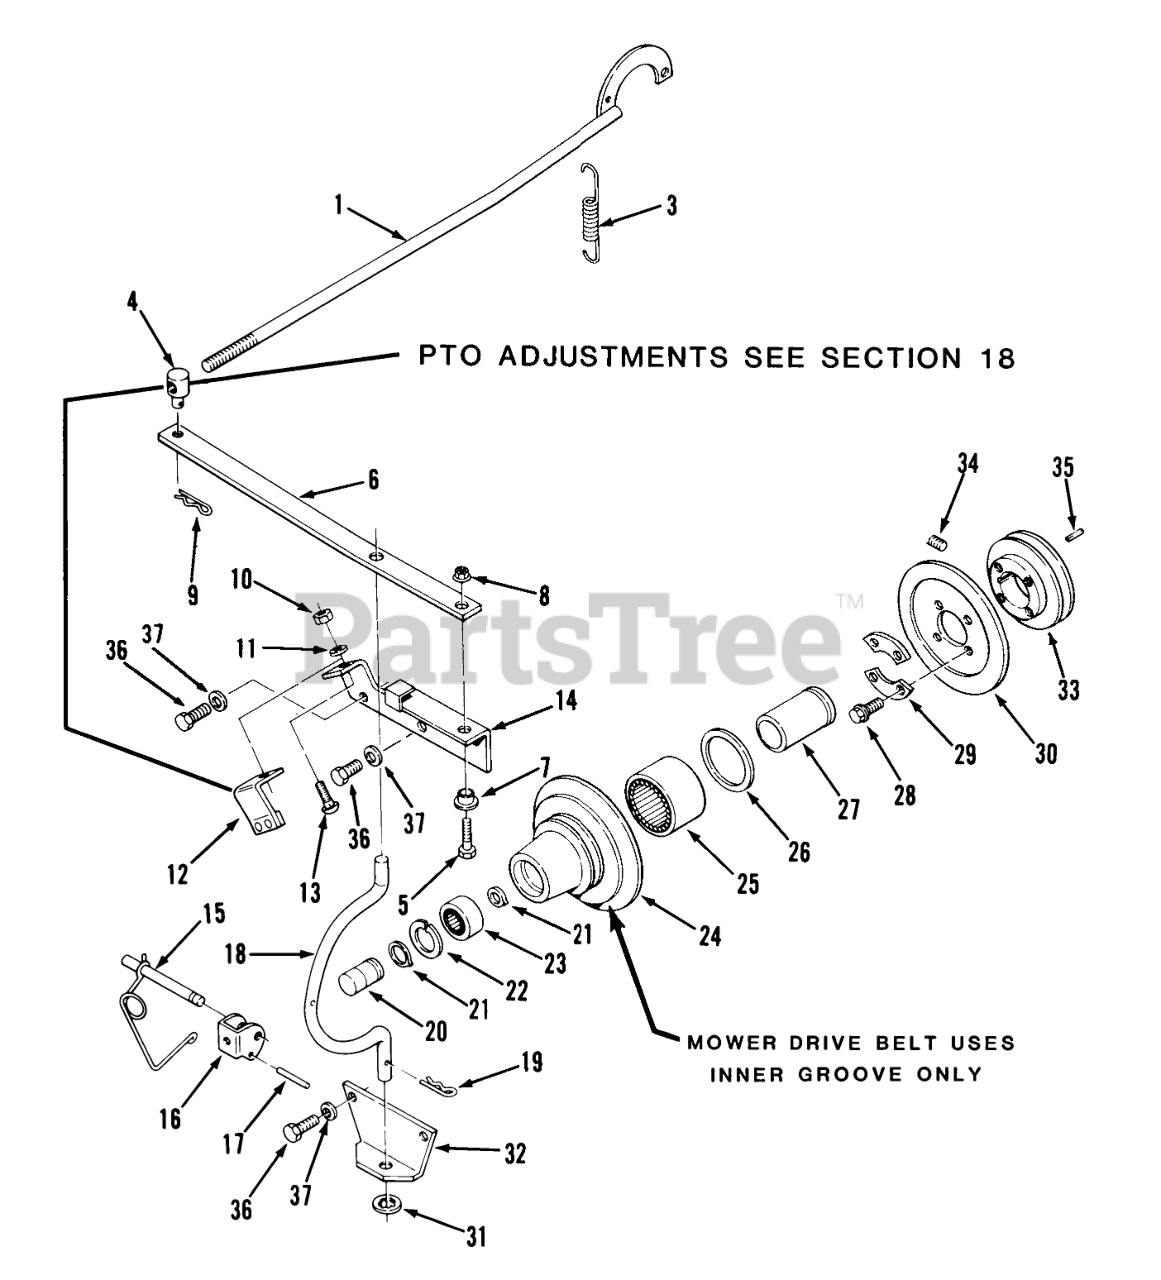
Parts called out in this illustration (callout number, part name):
1	PTO ROD 30209K
3	Spring
4	TRUNNION
5	BOLT
6	PTO ENG BRKT 30210K
7	SPACER-LIFT LINK
8	Nut
9	Hairpin Cotter
10	Nut
11	Washer
12	ASM-Bracket
13	Bolt-Carriage
14	Engine Bracket
15	LOCKING PIN ASM
16	CLEVIS B
18	ROD HOUSING
19	Hairpin
20	SHAFT-PTO
21	RING-SNAP, EXTERNAL
22	Ring-Snap
23	BEARING-BALL
24	Housing-Clutch
25	BRG-NEEDLE OPEN END
26	SEAL-OIL
27	RACE-BEARING
28	H H C S
29	RETAINER
30	Clutch Plate & Facing
31	RING-REINFORCED CIRC
32	Rod Support Housing
33	PULLEY
34	Set Screw
36	7/16-14 x 1 1/4 Bolt
37	LOCKWASHER
